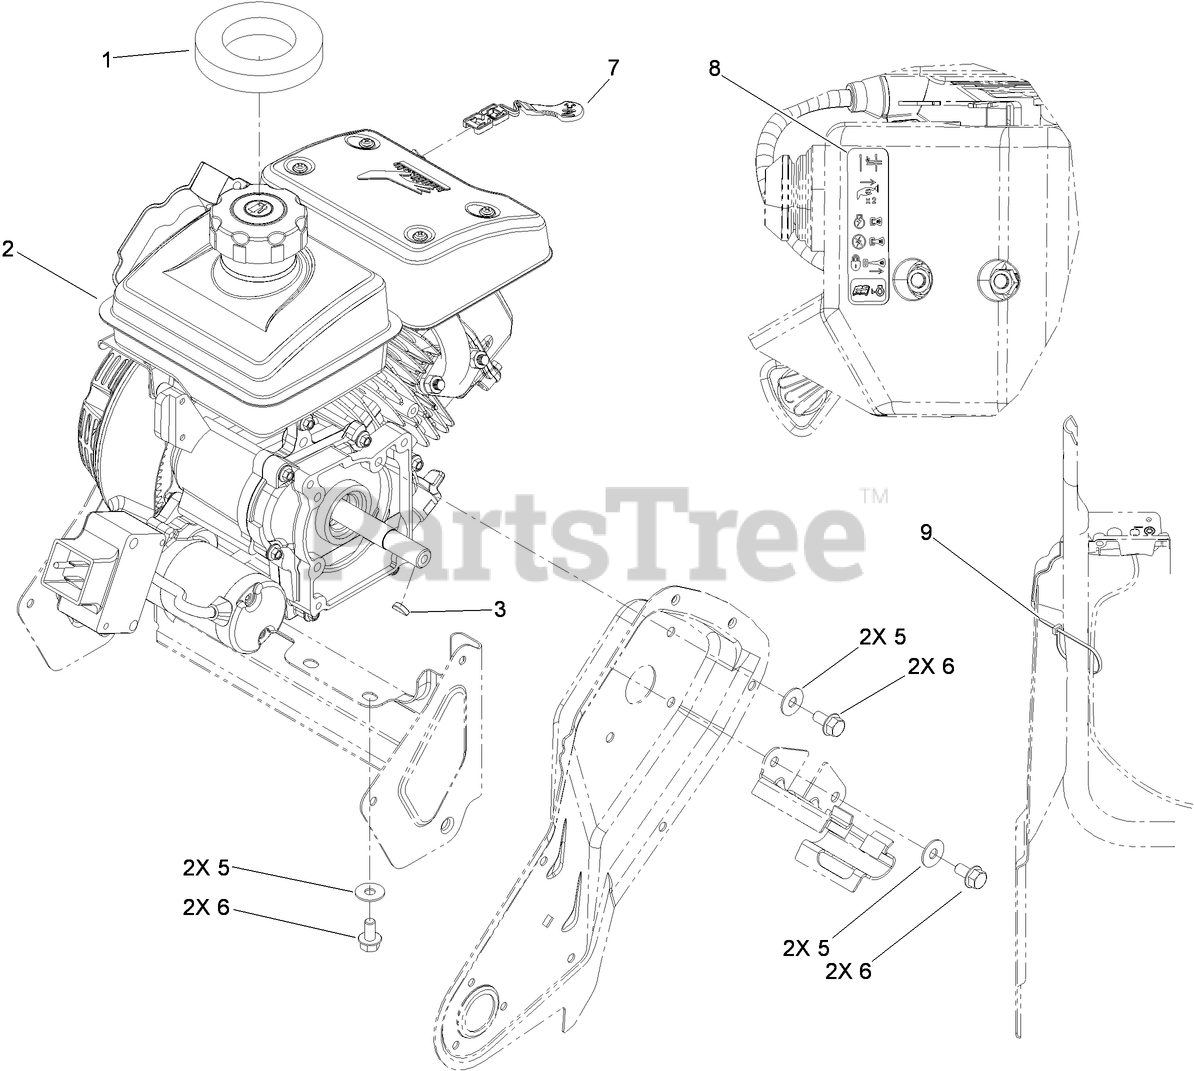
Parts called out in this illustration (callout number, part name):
1	SEAL-TANK
2	ENGINE-154FDS-1
3	KEY-WOODRUFF
5	WASHER-BELLEVILLE
6	SCREW-HHF
7	LEVER-CHOKE
8	DECAL-CONTROLS, ENGINE
9	TIE-CABLE
